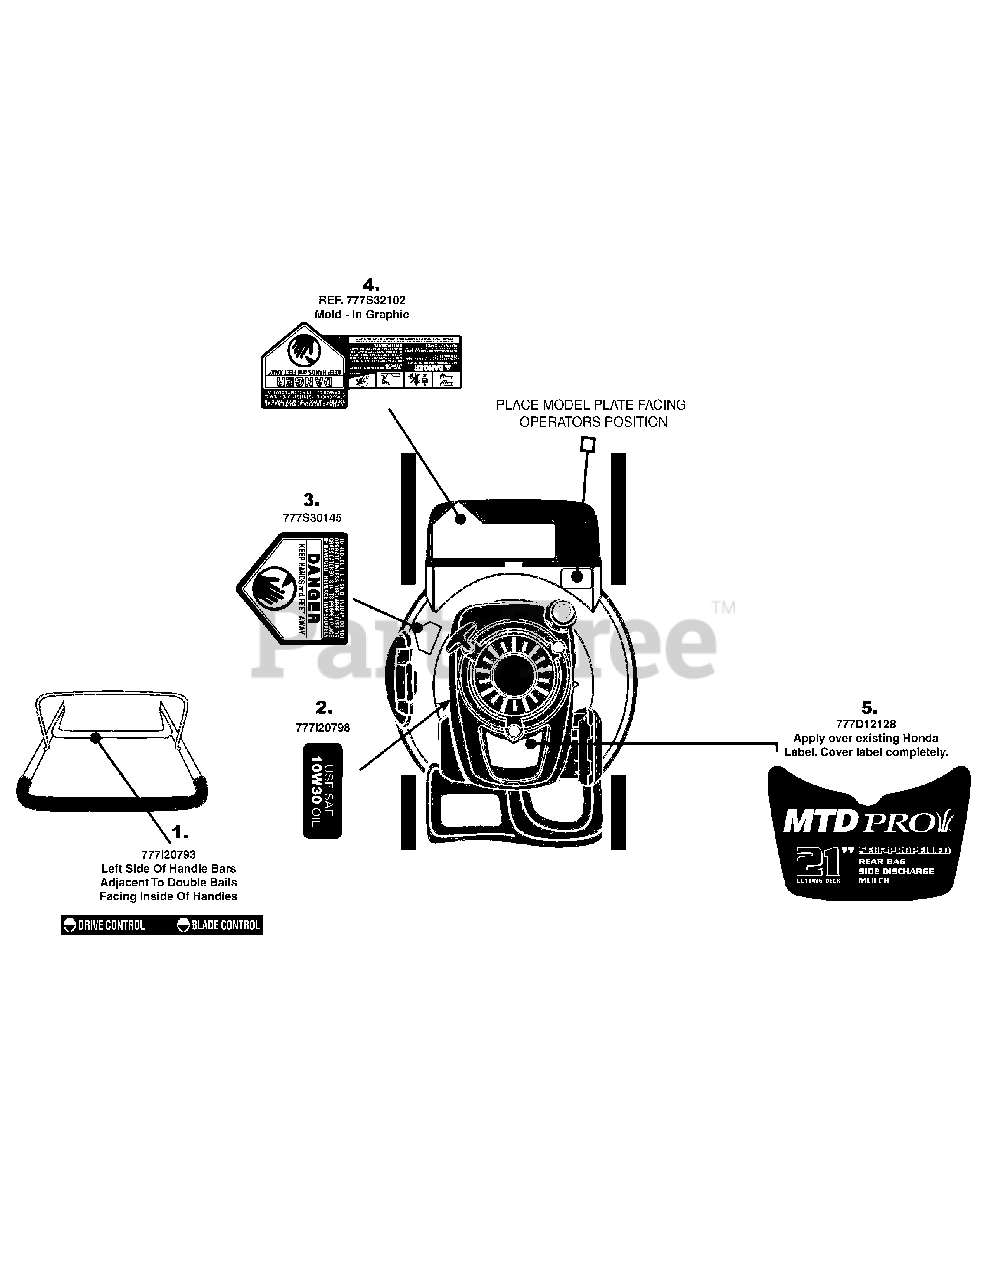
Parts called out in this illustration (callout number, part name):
1	LABEL-HANDLE
2	LABEL-SHROUD
3	LABEL
4	LABEL
5	LABEL-MOWER SHROUD MTD PRO 21" SP
